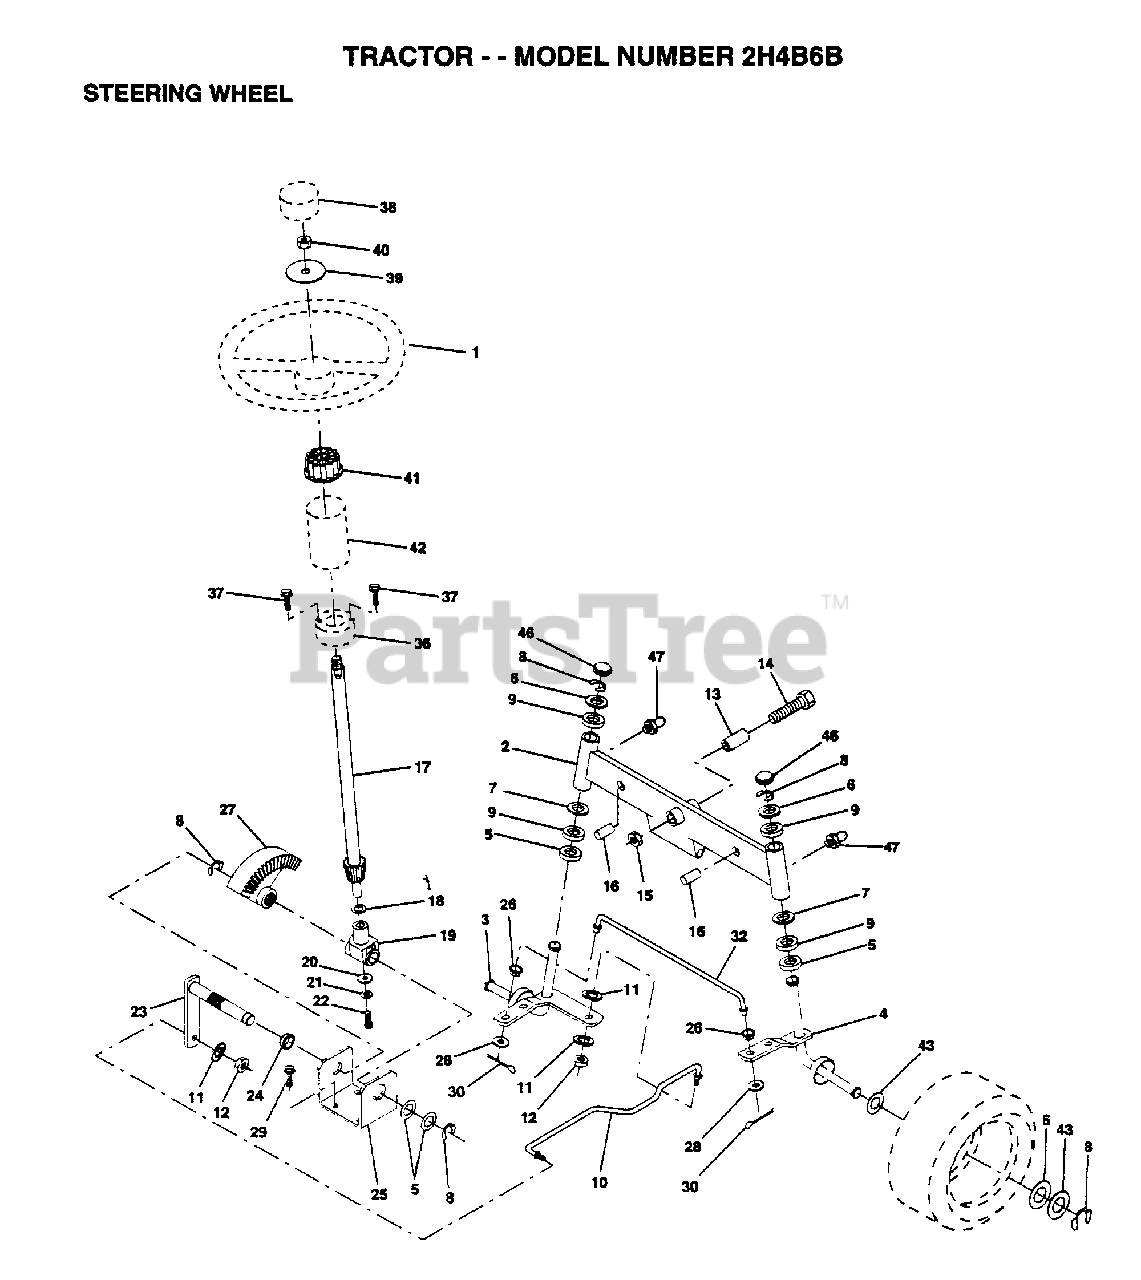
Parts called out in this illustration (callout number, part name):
2	AXLE ASM FRONT
3	SPINDLE LH
4	SPINDLE RH
5	WASHER .T
6	WASHER
7	WASHER
8	RING
9	COL. SRTG. BEAR.
11	LOCKWASHER
13	BEARING
14	BOLT HEX 5/8-11
15	"NUT-LOC,FLANGE LT"
16	AXLE PIN
17	SHAFT ASM
18	THRUST WASHER
19	SUPPORT.SHAFT
21	LOCKWASHER
22	"SCREW,SPECIAL"
24	NYLINER T
25	"BRKT,STEERING"
26	BUSHING.DRAGLINK
27	GEAR SECTOR
28	WASHER
29	SCREW
30	COTTER PIN
32	TIE ROD
38	ST WHL INSERT CAP
39	WASHER T
40	GRIPCO NUT
41	ADAPTER-WHEEL LT
42	PANEL DASH LH
43	WASHER
46	CAP
47	ZERK M
